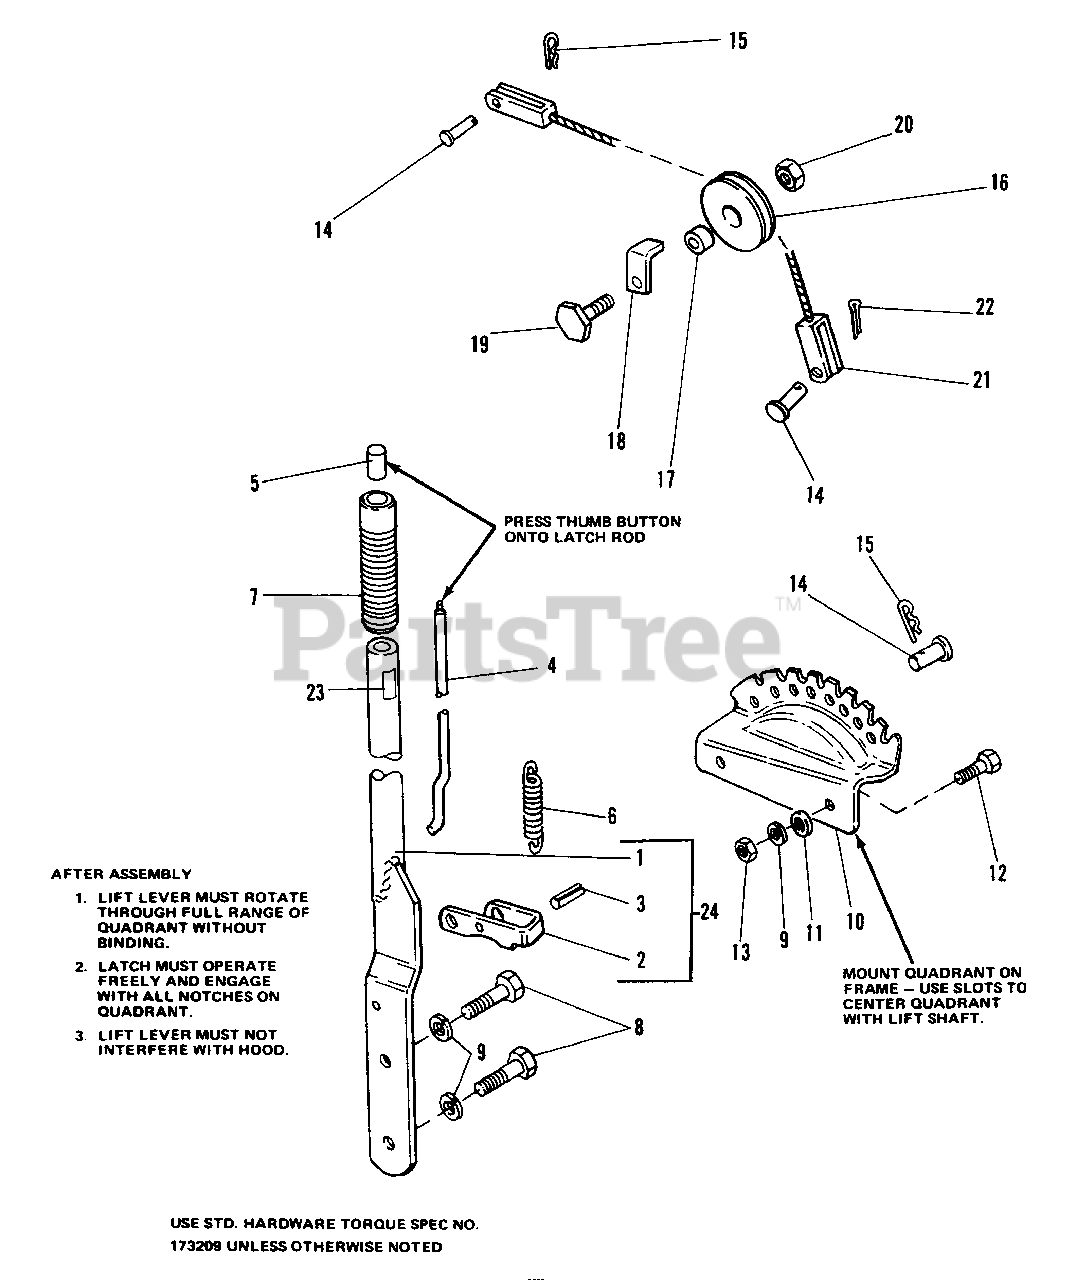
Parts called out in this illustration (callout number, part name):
1	LIFT LEVER ASSEMBLY
2	LATCH, Lift Lever
3	PIN, Spring, 3/8 x 1-1/4
4	ROD, Latch
7	GRIP
8	CAPSCREW, Hex Hd., 3/8-16 x 1
9	LOCKWASHER, 3/8
11	WASHER, 5/16
12	CAPSCREW, Hex Hd., 3/8-16 x 3/4
13	NUT, Hex, Full, 3/8-16
15	CLIP, Spring
18	GUARD, Cable
19	SCREW, Special
20	LOCKNUT, Hex, Jam, 3/8-16
21	LIFT CABLE ASSY
22	PIN, Cotter, 3/32 x 3/4
23	DECAL, Lift Lever
24	LIFT LEVER SUB ASSY.
